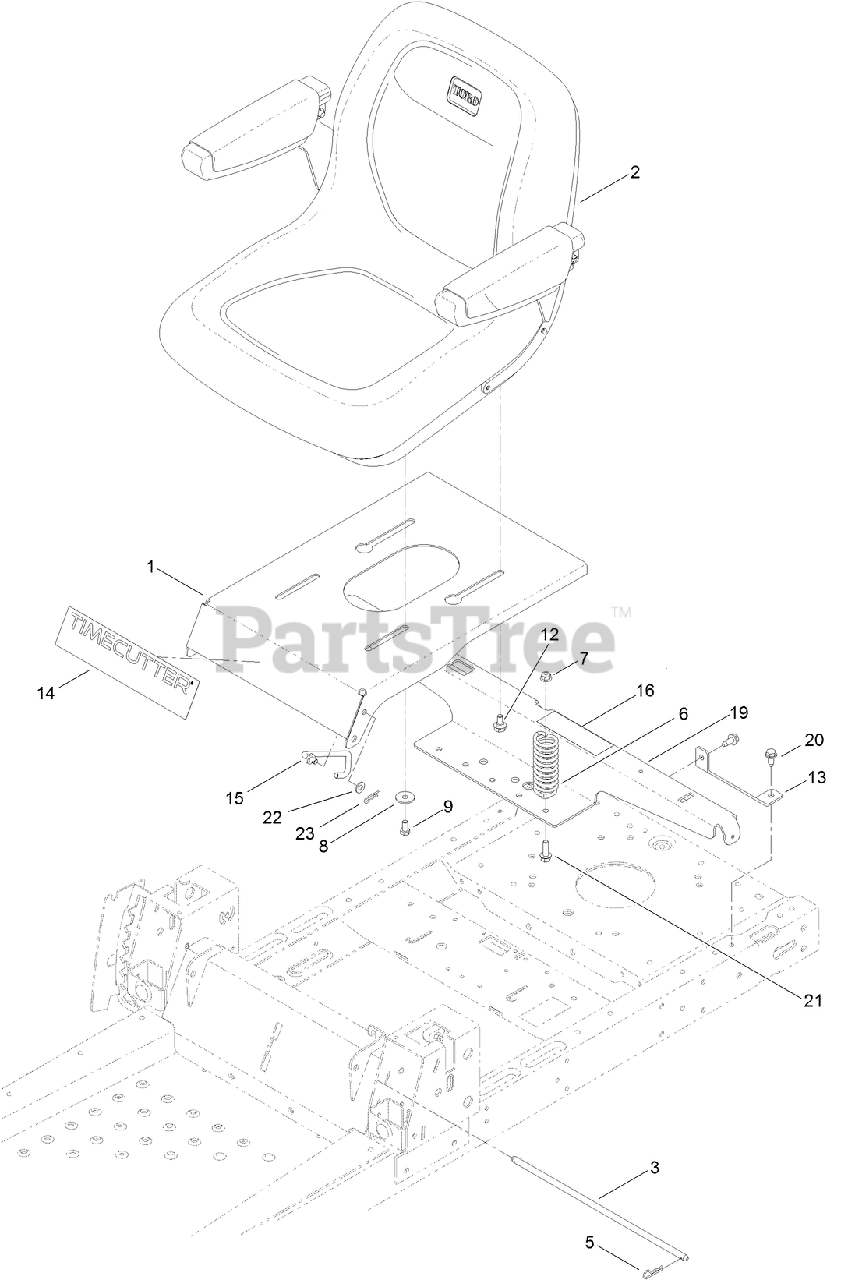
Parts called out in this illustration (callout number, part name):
2	SEAT-18 INCH
3	ROD-PIVOT, NARROW
5	PIN-COTTER
6	SPRING-COMPRESSION
7	NUT-HF, NI
8	WASHER-PIVOT
9	SCREW-HH
12	BOLT-SHOULDER,HFH
13	SUPPORT-TANK, REAR
14	DECAL-TIMECUTTER
15	STOP-SEAT
16	DECAL-SERVICE, CE
19	SUPPORT-POD
20	SCREW-HWHTF
21	SCREW-HHF
22	WASHER-PLAIN
